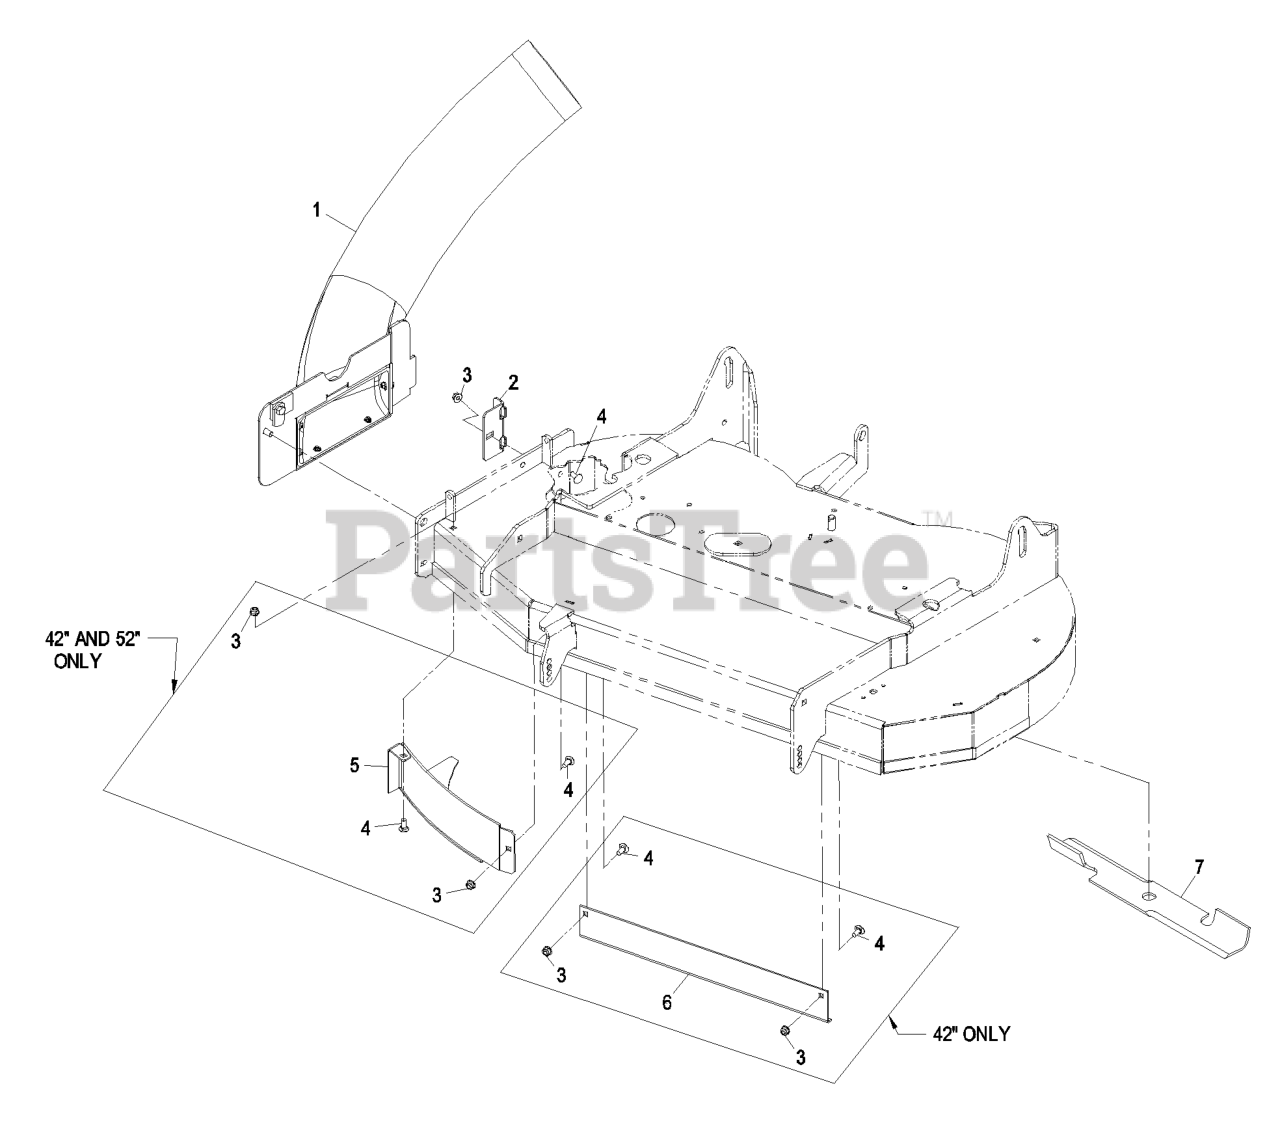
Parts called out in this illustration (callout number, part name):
1	ASM,TUBE AND FRAME
2	BRACKET,42 BAGGER MOUNT
3	NUT-HF, NI
4	SCREW-CARR
5	WLD,DISCHARGE BAFFLE
6	BAFFLE,CENTER BAGGER
7	Blade, Bagger 42"
